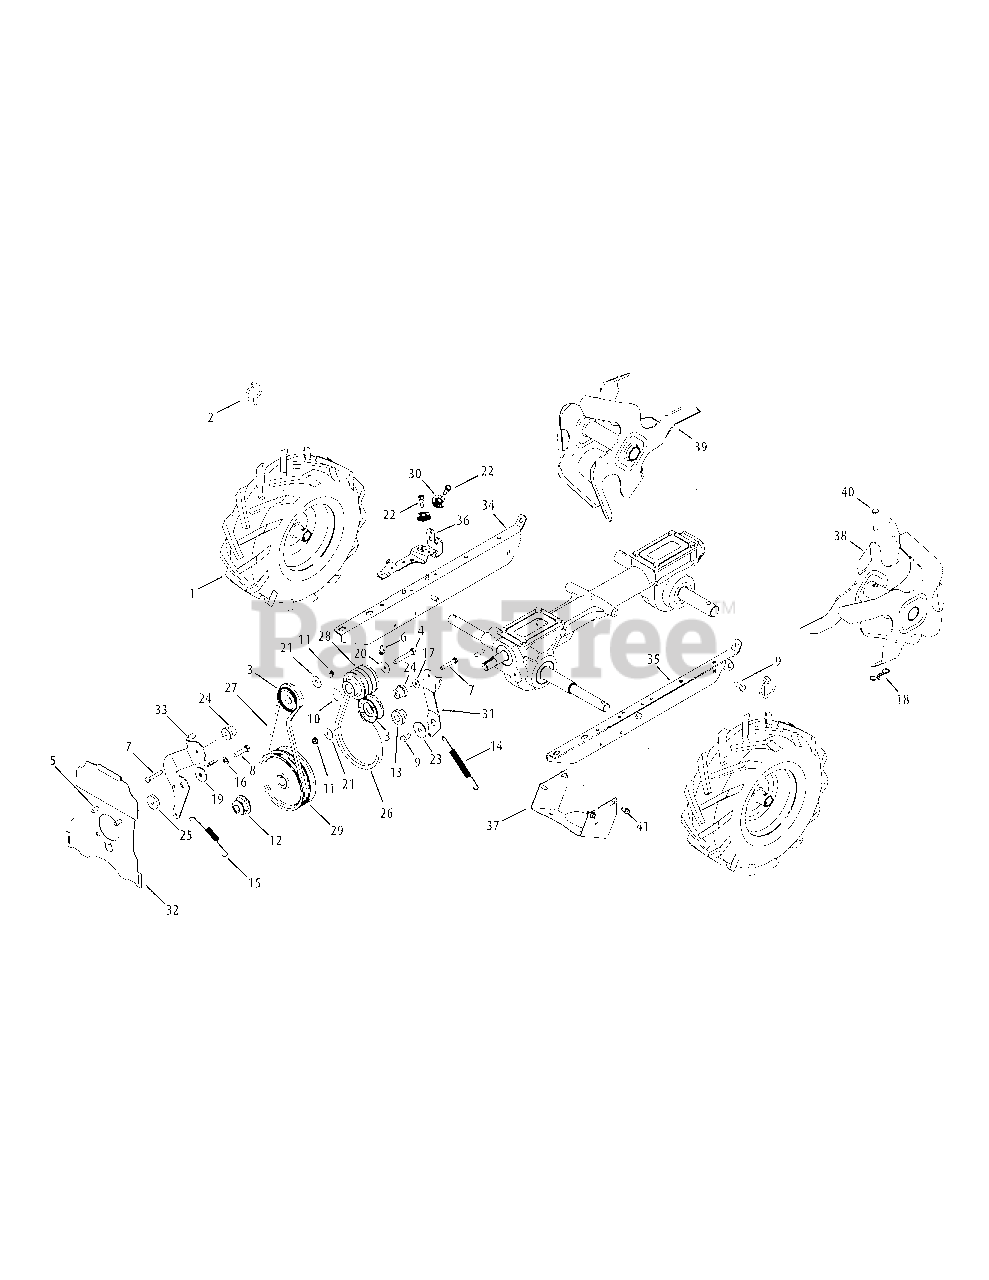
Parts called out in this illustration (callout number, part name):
1	Complete Wheel Asm, 13 x 5 x 6
2	Klik Pin
3	Idler Pulley Assembly
4	Hex Head Screw, 3/8-24 x 225
5	Hex Head Screw, 5/16-24 x 625
6	Self Tapping Screw, 1/4-20 x 500
7	Hex Head Screw, 1/4-20 x 150
8	Hex Head Screw, 5/16-18 x 125
9	Hex Head Screw, 5/16-18 x 75, Patch
10	Washer, Flat, 760 x 150 x 120
11	Nylon Hex Lock Nut, 1/4-20
12	Nut, 9/16-18, Flange Lock
13	Hub, 5/8 Spline
14	Extension Spring, 480 OD X 500 LG
15	Extension Spring
16	Lock Washer, 5/16
17	Washer, 28 x 74 x 063
18	Cotter Pin, Bow Tie
19	Flat Washer, 330 X 125 X 120
20	Bell Washer, 396 x 1140 x 095
21	Flat Washer, 265 x 10 x 030
22	Shoulder Screw, 342 x 335 1/4-28
23	Pivot Idler Spacer
24	Shoulder Spacer, 260 x 785 x 538
25	Pivot Idler Spacer
26	V-Belt, 4L x 25375 Long
27	V-Belt, 3L x 29125 Long
28	Engine Pulley
29	Transmission Pulley
30	Cable Roller
31	Idler Bracket, Forward
32	Cover Plate
33	Idler Bracket, Reverse
34	Mounting Frame, RH
35	Mounting Frame, LH
36	Pulley Bracket
37	Pulley Shield
38	Tine Assembly, LH
39	Tine Assembly, RH
40	Clevis Pin, 375 x 175
41	Self Tapping Screw, 1/4-14 x 625
